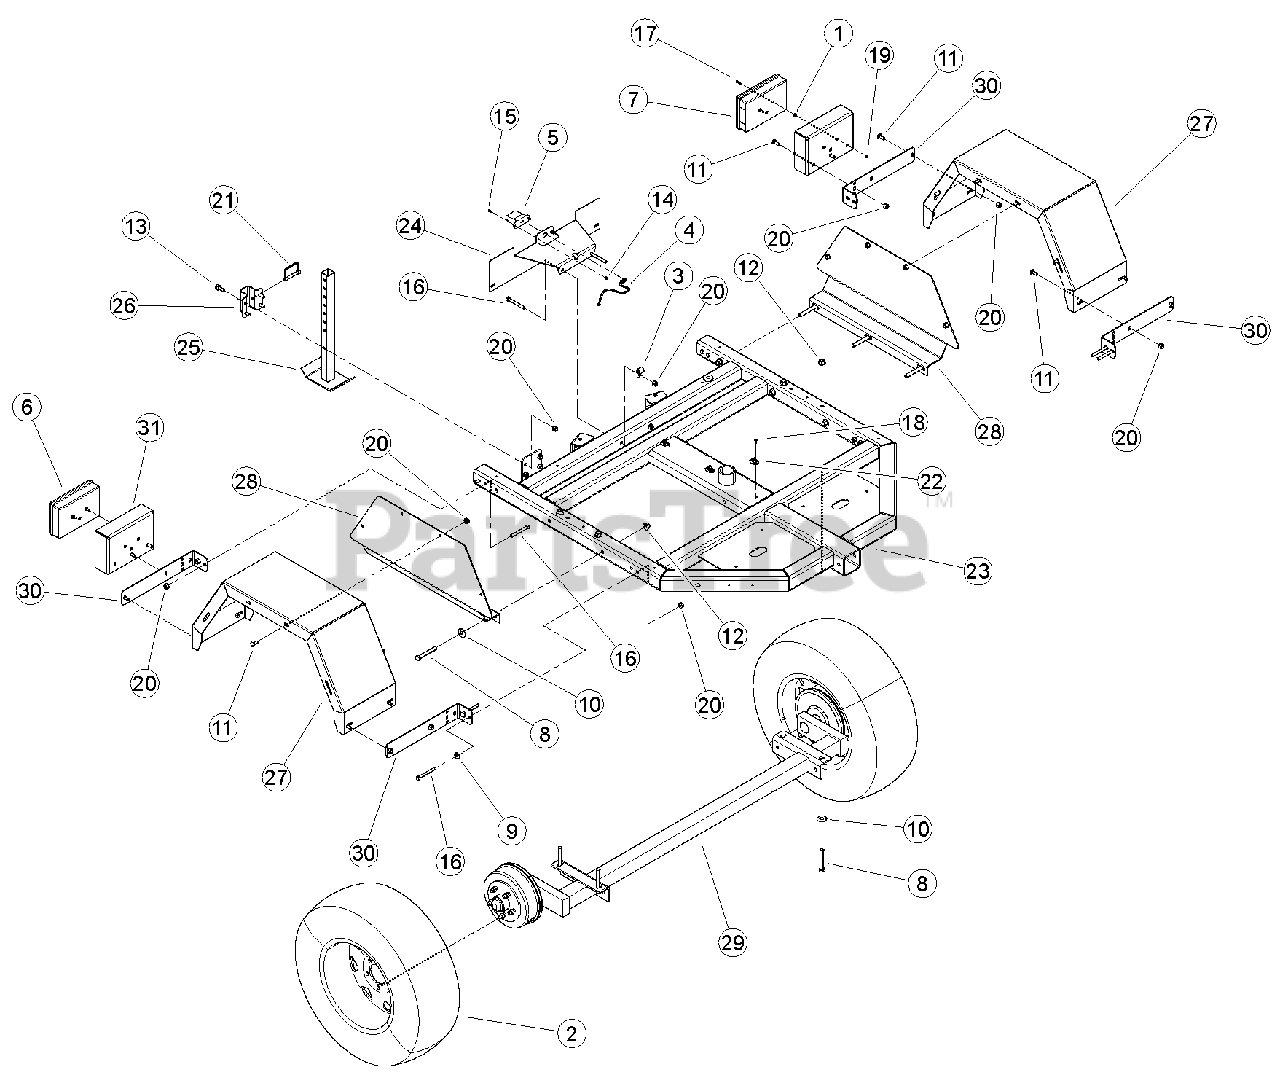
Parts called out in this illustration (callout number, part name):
1	GROMMET, 1/4 X 5/8 RUBBER
2	ASSEMBLY, 15 INCH TIRE + WHEEL
3	CLAMP, 9/16 COATED
4	PLUG, 12 VOLT LIGHT
5	LIGHT, LICENSE PLATE
6	LIGHT, TAIL RH
7	LIGHT, TAIL LH
8	BOLT, 1/2 X 3-1/2" GR5 HEX HD ZP
9	WASHER, 3/8" FLAT ZP
10	WASHER, 1/2" FLAT ZP
11	BOLT, 3/8 X 1" GR5 CRG NC ZP
12	NUT, 1/2-13 NYLOCK FLANGE
13	BOLT, 3/8 X 1 FLANGE NC
14	NUT, 10/24 NYLOCK TYPE NM ZP
15	SCREW,MCH 10-24 X 1/2" PAN HD PH ZP
16	BOLT, 3/8 X 3-1/4 HEX HD GR5 ZP
17	BOLT, 10-24 X 3/4" HHCS GR8 PLAIN
18	RIVET, AL BLIND 1/4 X 3/4 DOME HEAD
19	NUT, #10-24 K-LOCK ZP
20	NUT, 3/8-16 NYLOCK FLANGE
21	PIN, 3/8 X 2-3/4" SNAP
22	CLAMP, CABLE MOUNT
23	WELDMENT, 8" CHIPPER TRAILER
24	BRACKET, CE LICENSE PLATE MOUNT
25	WELDMENT, REAR STABILIZER
26	GUIDE, TRAILER SUPPORT
27	FENDER, CHIPPER
28	BRACKET, FENDER
29	ASSEMBLY, 2,500 LB TORSION AXLE
30	ANGLE, FENDER GUSSET
31	BRACKET, TAIL LIGHT
